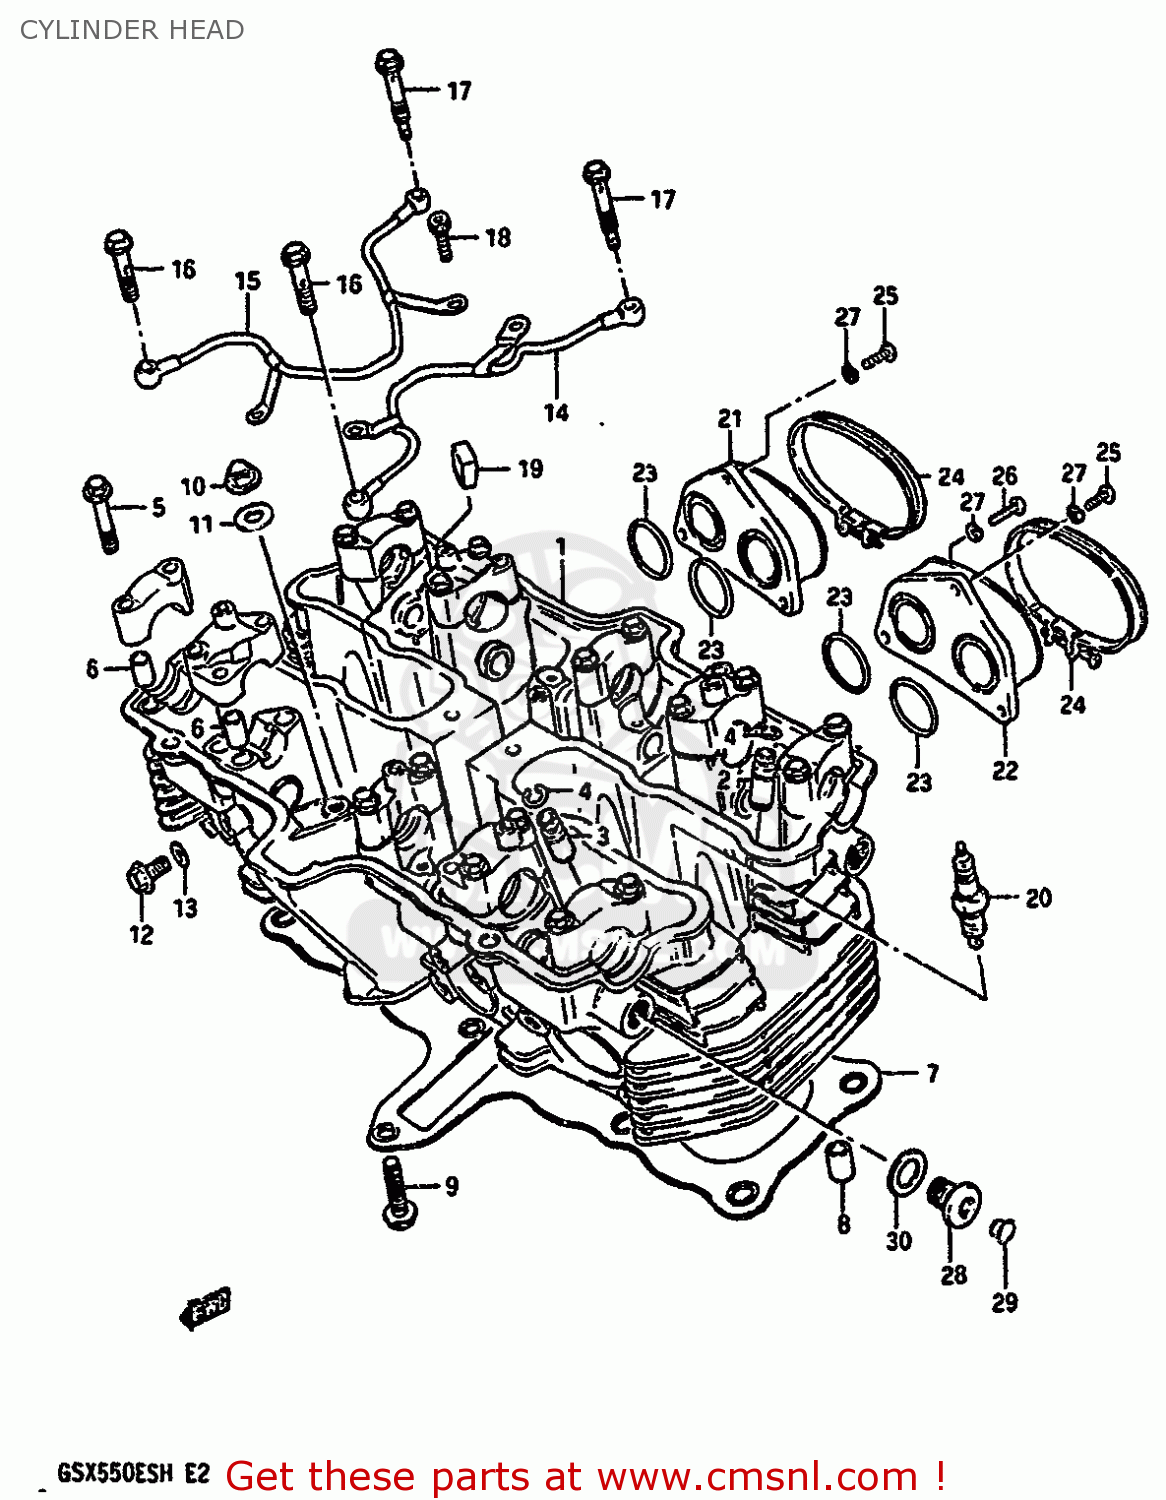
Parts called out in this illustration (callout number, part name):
1	HEAD ASSEMBLY,CYLINDER
2	GUIDE,VALVE
3	GUIDE,VALVE
4	RING,SNAP
5	BOLT(6X39)
6	PIN(6.2X8X11)
7	GASKET,CYLINDER HEAD (NAS)
8	PIN
9	BOLT
10	NUT
11	GASKET(8.5X20X2.3) (NAS)
12	BOLT
13	GASKET(6.2X13X1.2) (NAS)
14	PIPE,OIL CYLINDER HEAD
15	PIPE,OIL CYLINDER HEAD
16	UNION
17	BOLT,UNION
18	BOLT, 6X16
19	PAD,CYLINDER
20	SPARK PLUG D9EA
21	PIPE,INTAKE,R
22	PIPE,INTAKE,L
23	O-RING (D:2.4 ID:29.7)
24	CLAMP
25	SCREW
26	SCREW
27	WASHER,LOCK
28	PLUG
29	CAP(OD:12)
30	GASKET(14X19.2X2) (NAS)
